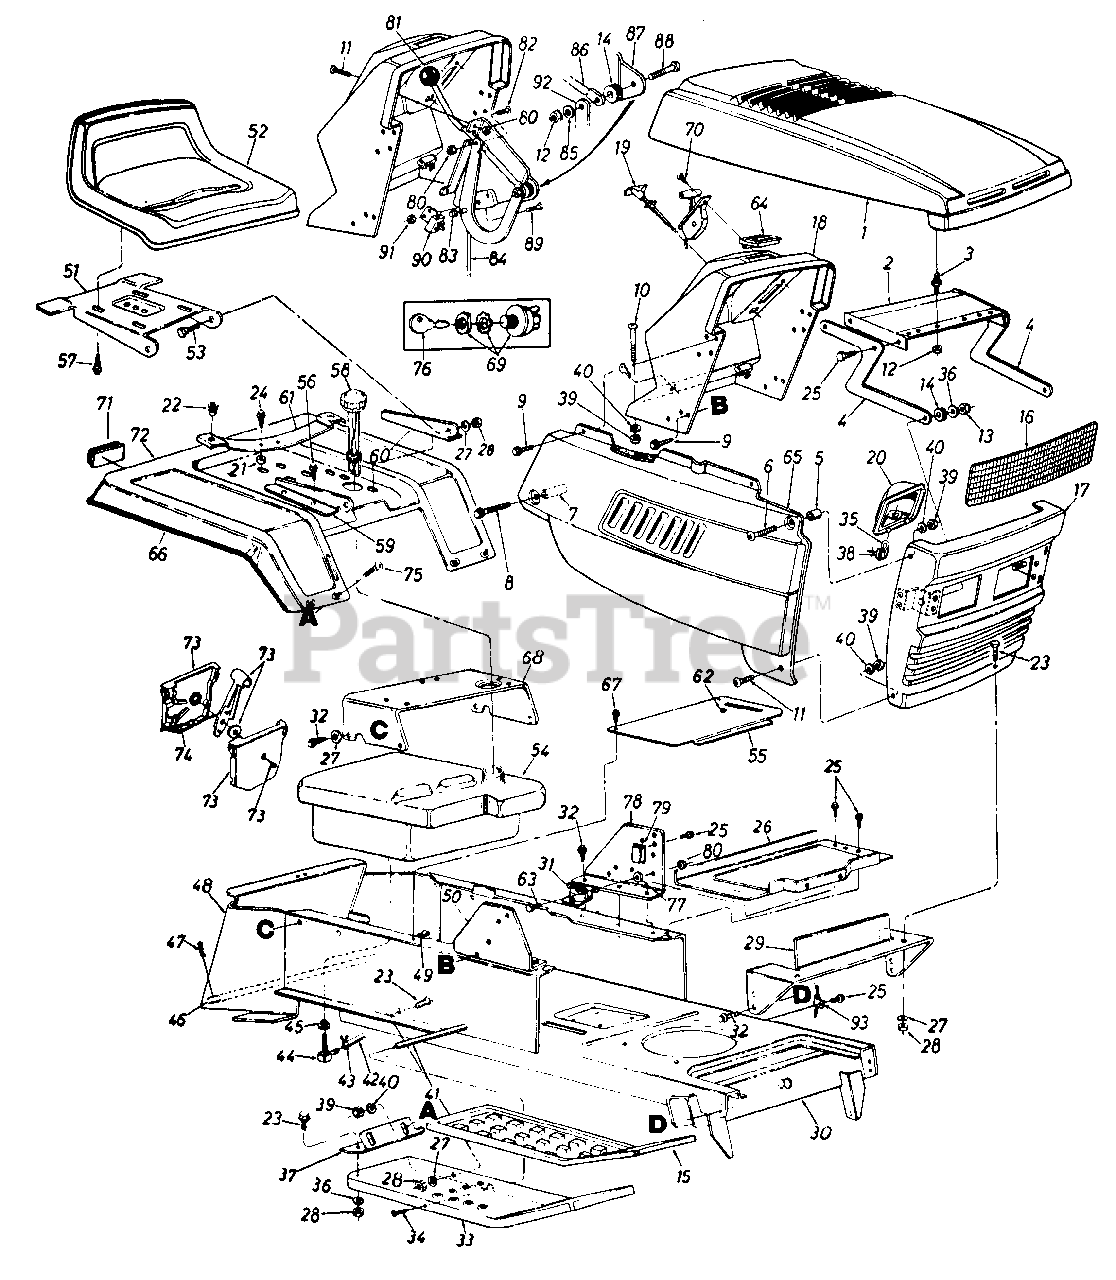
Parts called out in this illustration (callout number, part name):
2	Hood Plate
3	Double Ended Stud 1/4-20 Thd.
4	Hood Hinge
5	Spacer .255" I.D. x .375"
6	Truss Hd. Mach. Scr. 1/4-20 Thd.
7	Spacer .26" I.D. x .375"
8	Hex Wash. TT-Tap Scr. 1/4 -20 x 1 . 75 " Lg .
9	Hex TT-Tap Scr. 1/4-20 x .75" Lg.
10	Truss Mach. Scr. 1/4-20 x 1.5" Lg.
11	Truss Mach. Scr. 1/4-20 x .5" Lg.
12	Hex Patch L-Nut 1/4-20 Thd.
13	Hex L-Nut 5/16-18 Thd.
14	Rubber Washer
15	Rubber Foot Pad
16	Headlight Lens
19	Choke Control
20	Headlight Housing
21	Spacer.38" I.D.
22	Grommet
23	Hex Bolt 5/16-18 x .75" Lg.
24	Hex Tap Scr. 5/16-18 x 1.25" Lg.
25	Hex Wash. Hd. Scr. 1/4" x .5" Lg.
26	Battery Carrier
27	L-Wash. 5/16" I.D.
28	Hex Nut 5/16-18 Thd.
29	Grille Mounting Bracket
30	Lower Frame Ass'y.
31	Solenoid
32	Hex Hd. Rolling Scr. 5/16-24 x.75" Lg.
35	Lamp
36	Bell-Wash. .34" I.D. x .87"
39	Hex Nut 1/4-20 Thd.
40	L-Wash. 1/4" I.D.
41	Running Board Rod
42	Fuel Line 40" Lg.
43	Hose Clamp 3/8" Lg.
44	90ø Nipple
45	Bushing
46	Hitch Rod
47	Internal Cotter Pin
50	Dash Support Brkt.-R.H.
51	Seat Pivot Bracket
52	Seat Ass'y.
53	Shld. Bolt .437" Dia. x .162"
54	Fuel Tank
55	Transmission Cover Ass'y.
56	Hex Wash. Hd. Self-Tap Scr. 5/16-18 x .5" Lg.
57	Hex Wash. Hd. AB-Tap Scr. 3/8 x .75" Lg.
58	Gas Cap w/Gauge
59	Seat Bracket-R.H.
60	Seat Bracket-L.H.
61	Seat Spring
62	Snap Bushing
63	Hex Bolt 1/4-20 x .5" Lg.
64	Ammeter
67	Truss Mach. B-Tap Scr. #10 x .5" Lg.
68	Seat Mounting Channel
69	Ignition Switch
70	Truss Mach. AB-Tap Scr. #10 x .5" Lg.
71	Reflector
74	Throttle Control Wire
75	Carriage Bolt 1/4-20 x .5" Lg.
76	Key
77	Ext. L-Wash. .44" I.D.
78	Dash Support Brkt.-L.H.
79	Circuit Breaker
80	Hex Sems Nut 1/4-20 Thd.
81	Ball Knob
82	Hex Bolt 1/4-20 x .62" Lg.
83	Push Nut
84	PTO Rod
85	Fl-Wash. .281" I.D. x .73"
86	PTO Lever
87	Deck Clutch Control Brkt.
88	Hex Bolt 1/4-20 x 1.25" Lg.
89	Truss Mach. Scr. #10-24 x .5" Lg.
90	Safety Switch
91	Hex Nut #10-24 Thd.
92	PTO Bracket
93	Battery Hose Clamp
